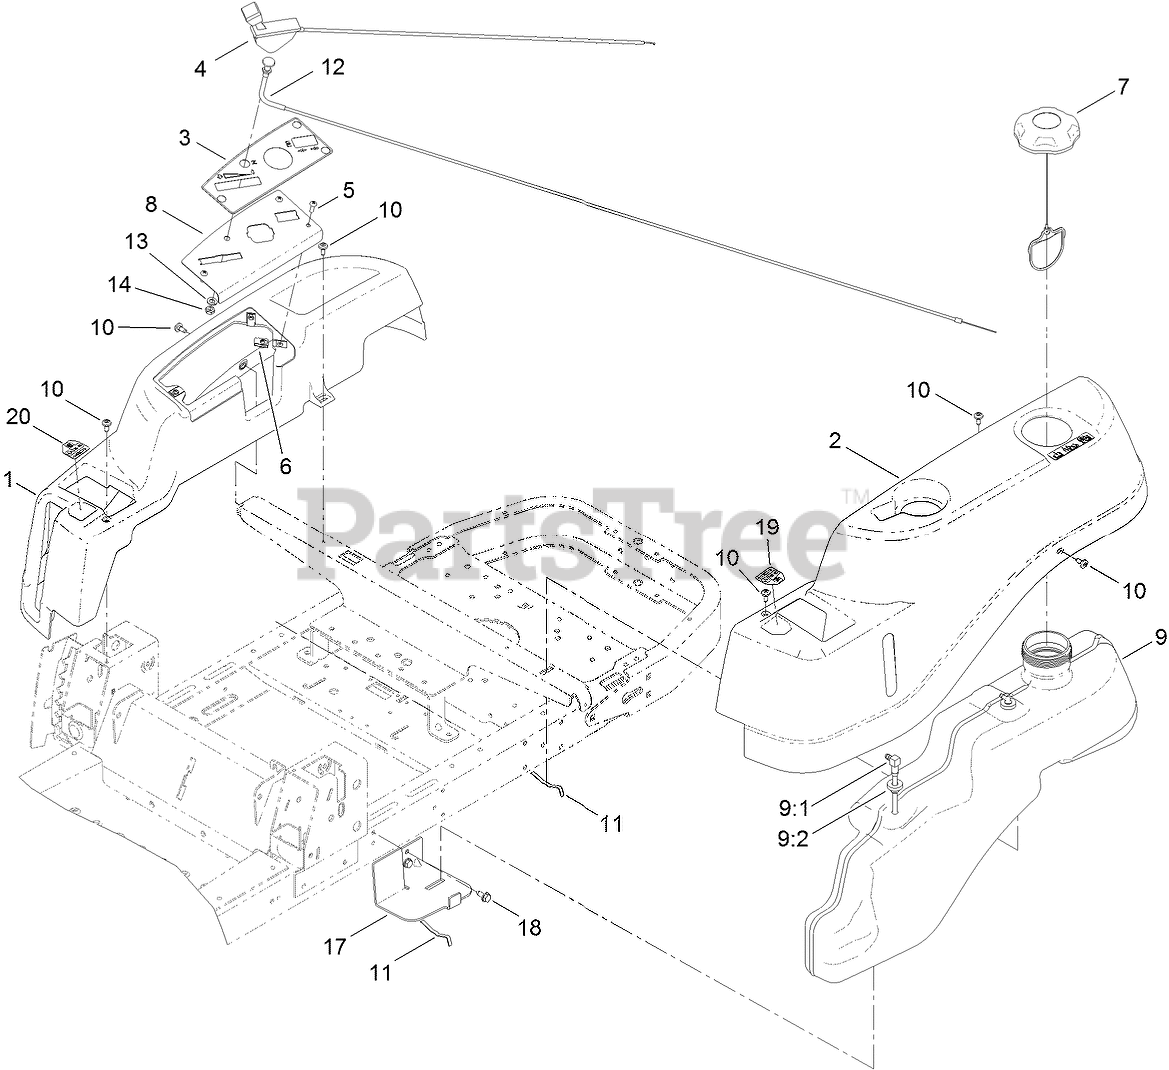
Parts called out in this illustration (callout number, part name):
1	POD-RH
2	POD-LH
3	DECAL-PANEL, CONTROL
4	CABLE-THROTTLE
5	SCREW-PRH
7	CAP-FUEL, RATCHETING
8	PLATE-CONTROL
9	FUEL TANK ASM
9:1	TUBE-DROP
9:2	BUSHING
10	SCREW-SHOULDER
11	SPRING
12	CABLE-CHOKE
13	WASHER-LOCK
14	NUT-HJ
17	SUPPORT-TANK, FRONT
18	SCREW-HWHTF
19	DECAL-CONTROL LEVER, LH
20	DECAL-CONTROL LEVER, RH
